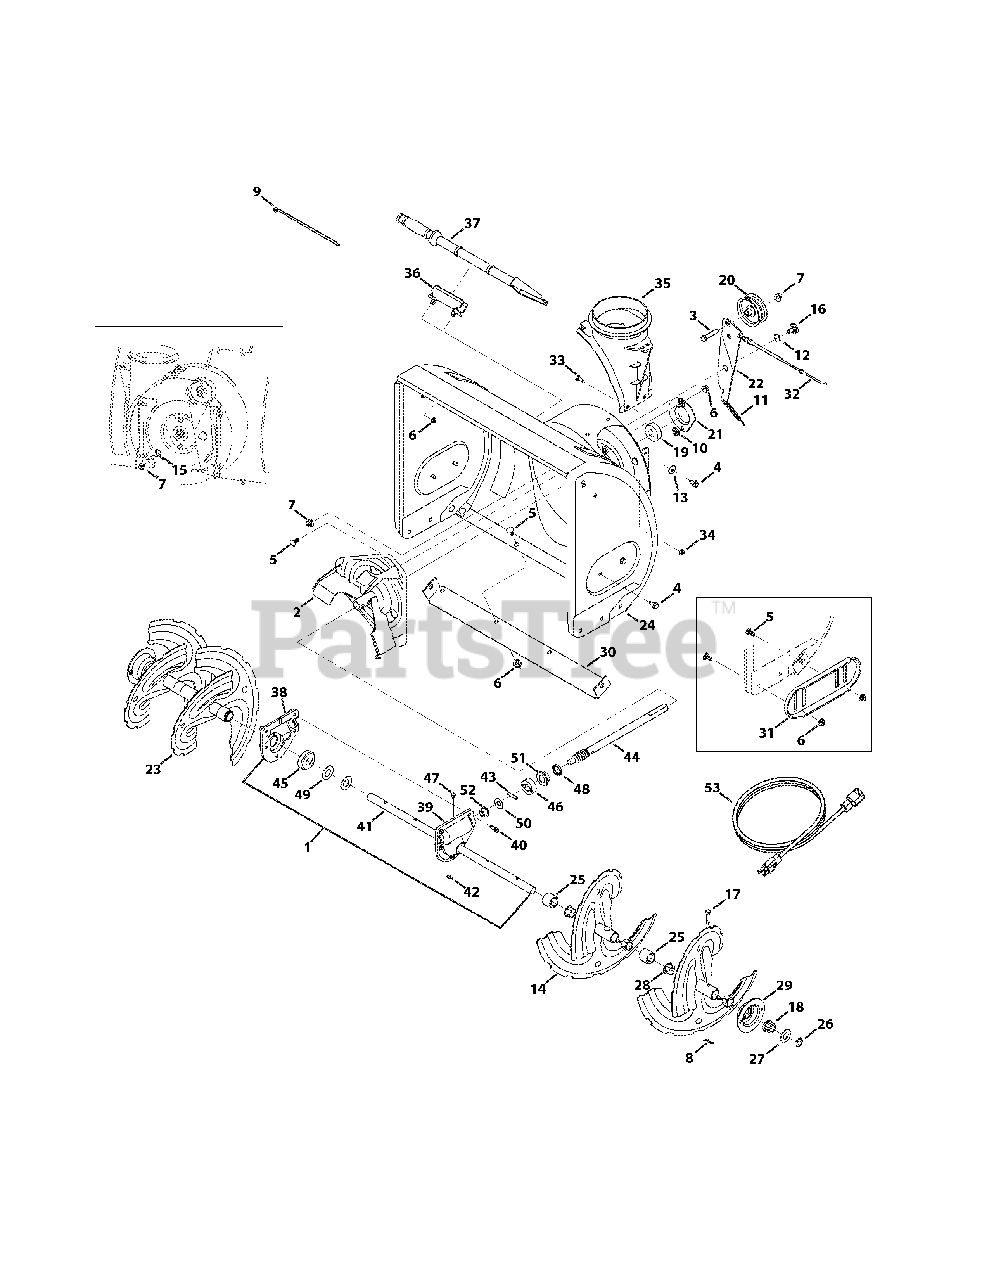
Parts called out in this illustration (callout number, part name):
1	Auger Gearbox 28",
2	Impeller Assembly, 12" Dia.
3	Hex Head Screw, 3/8-16 x 1.75
4	Screw, 5/16-18 x .750
5	Bolt, Carriage, 5/16-18 x .750
6	Nut, Flange lock, 5/16-18
7	Nut, Flange lock, 3/8-16
8	Bow-Tie Cotter Pin
9	Cable Tie, 7"
10	Nut, Push-on, .25 Dia.
11	Extension Spring, .38 x 4.59
12	Washer, Wave, .625 x .885
13	Washer, Bell, .340 x .872
14	Spiral Assembly, LH
15	Bolt, Shoulder, .496 x .336 x 3/8-16
16	Screw, Shoulder, .625 x .17 x 3/8-16
17	Shear Pin, .25 x 1.50
18	Hex Flange Bearing
19	Bearing, Ball, .75 x 1.85
20	Pulley, Idler, Flat, 2.75
21	Bearing, 1.85 ID
22	Auger Idler Bracket
23	Spiral Assembly, RH
24	Auger Housing Assembly, 28"
25	Spacer, 1.25 x .75 x 1.00
26	E-Ring, .750
27	Washer, Flat, .76 x 1.49
28	Bushing, Flange, .800 x .910
29	Hex Bearing Housing
30	Shave Plate, 28"
31	Deluxe Skid Shoe
32	Auger Drive Clutch Cable
33	Screw, Carriage, 1/4-20 x .75
34	Nut, Flange lock, 1/4-20
35	Chute Adapter
36	Clean-Out Tool Mount
37	Clean-Out Tool
38	Reducer, RH
39	Reducer, LH
40	Screw, 1/4-20 x 0.750
41	Auger Axle, 28"
42	Key, Hi-Pro, 3/16 x 5/8
43	Dowel Pin, .25 x 1.25
44	Worm Shaft, .75
45	Gear Worm, 20T
46	Collar Thrust, .756 x .600
47	Plug, 1/4 x .437
48	Oil Seal, .75 x 1.131 x .188
49	Washer, Flat, .760 x 1.50
50	Washer, Flat, .51 x 1.12
51	Bearing, Flange, .75 x 1.00 x .59
52	Bearing, Flange, .50 x .75 x .59
53	3-Prong Extension Cord
